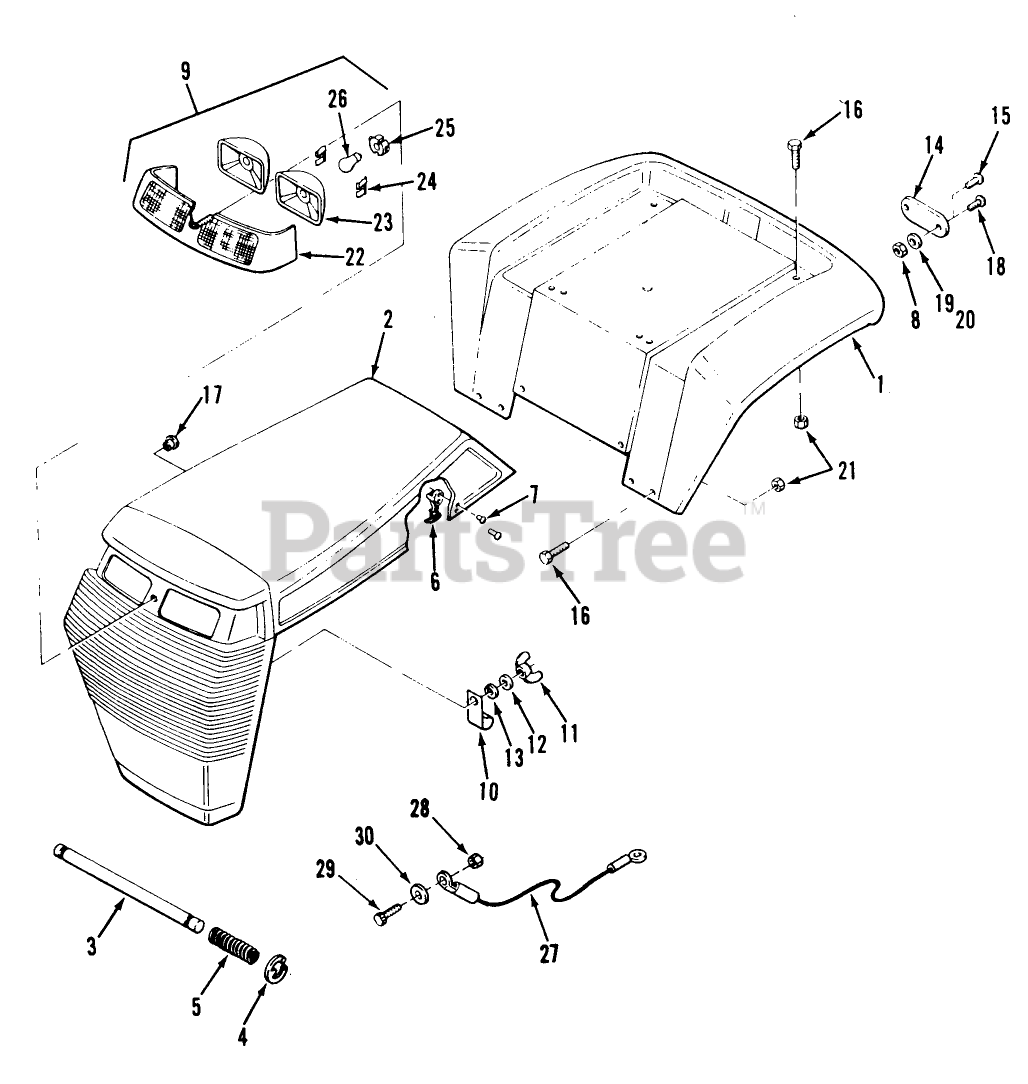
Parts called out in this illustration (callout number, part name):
1	FENDER *R
5	SPRING
7	RIVET -4
10	J-CLIP
12	WASHER
17	BUSHING-NYLON 1.093
19	WASHER
23	LIGHT POD
24	RETAINER
25	SOCKET-HEADLIGHT
26	BULB
